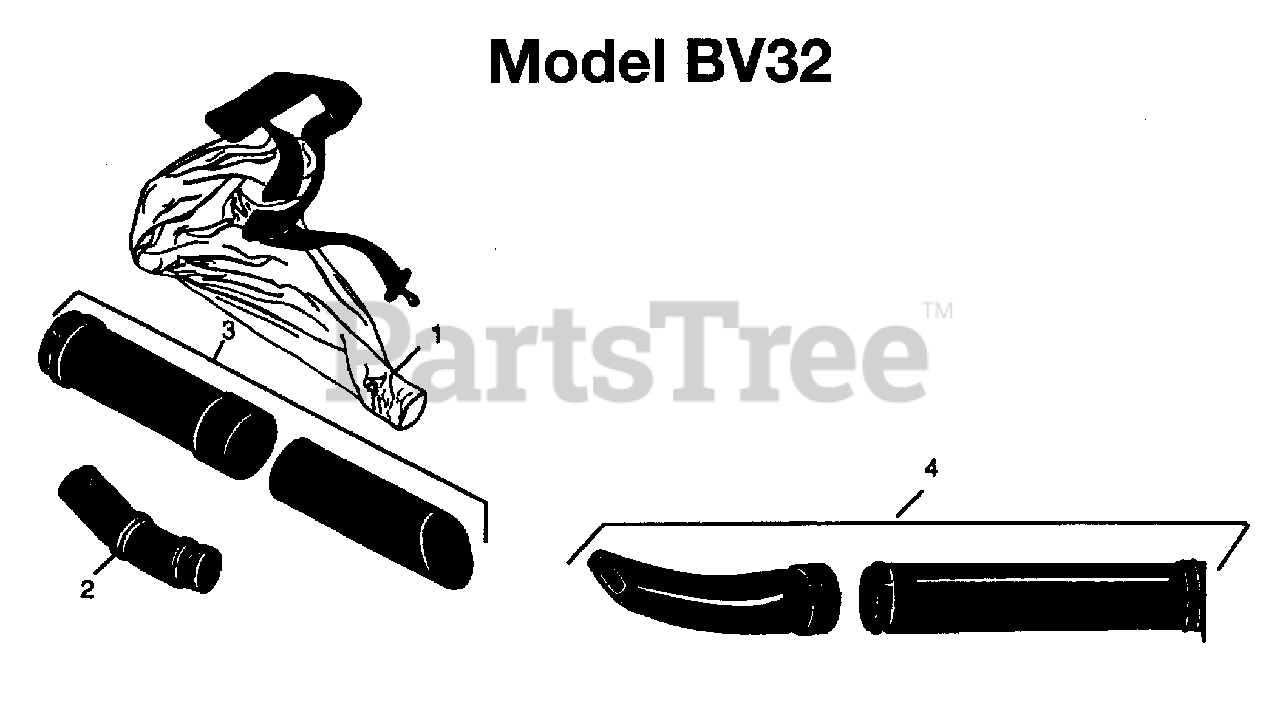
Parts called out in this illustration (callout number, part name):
1	COLLECTION BAG W/ STRAP
2	ELBOW TUBE
3	VAC TUBE SET
4	TUBE & NOZZLE ASS'Y
